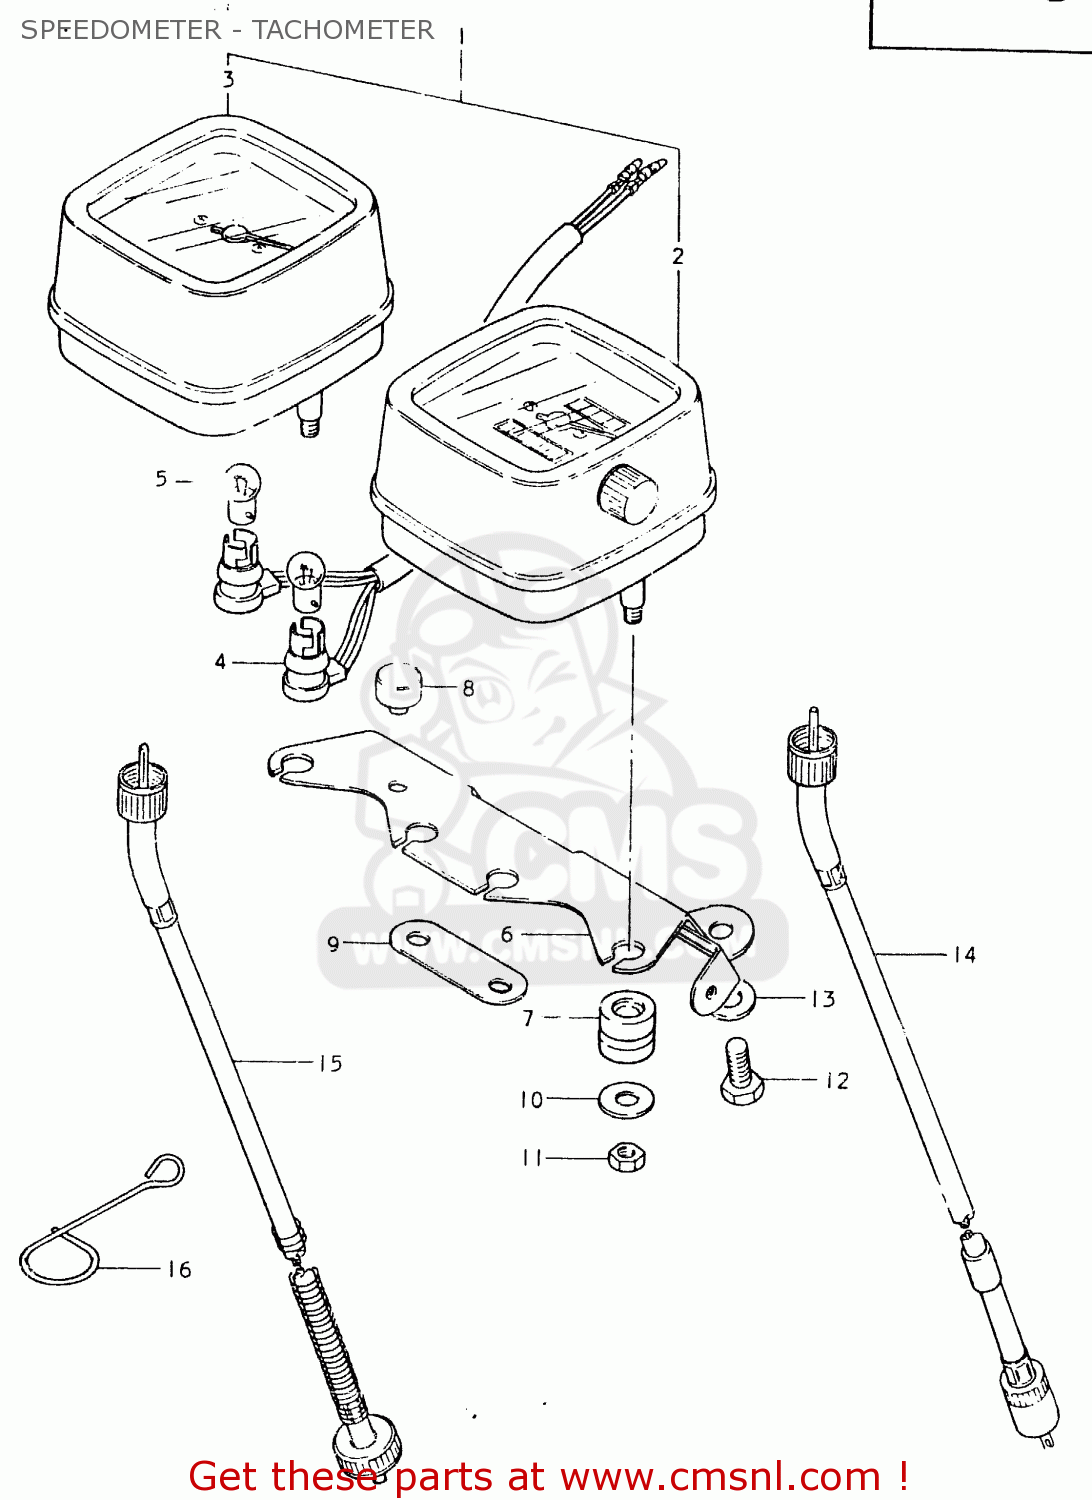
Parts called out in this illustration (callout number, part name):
1	SPEEDO/TACHOMETER ASSY (KILO SCALE)
2	SPEEDOMETER (KILO)
3	TACHOMETER
4	SOCKET
5	BULB(6V1.7W,STANLEY,A61A)
6	BRACKET
7	CUSHION
8	CUSHION,METER
9	PLATE,CONNECTING
10	WASHER,METER
11	NUT
12	BOLT, UPPER
13	WASHER
14	CABLE ASSEMBLY,SPEEDOMETER
15	CABLE, TACHOMETER
16	GUIDE,TACHOMETER CABLE
